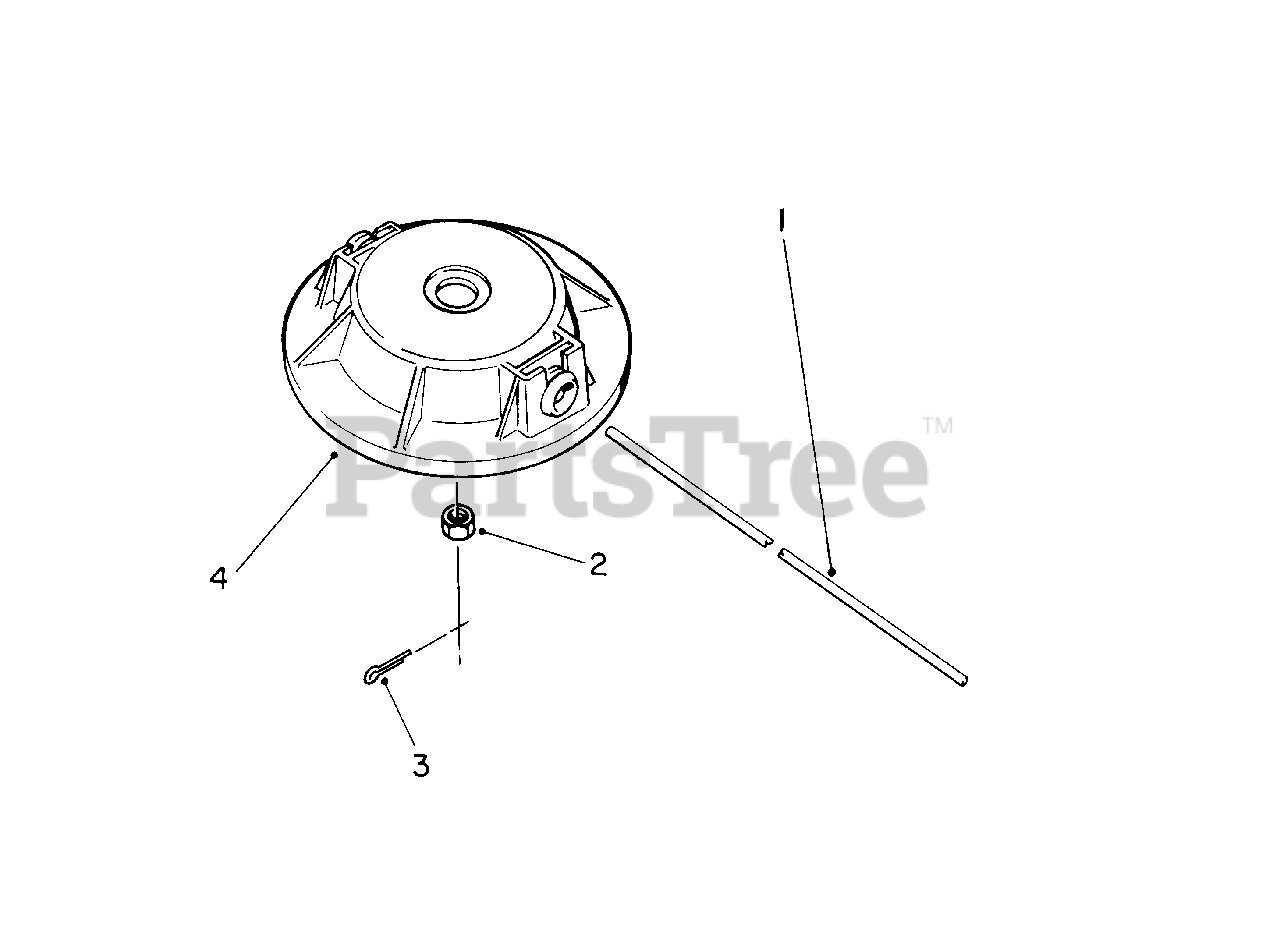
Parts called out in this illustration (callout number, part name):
1	Line-Cutting .105 Dia.
2	Nut Hex. L.H.
3	Pin-Cotter
4	Cutter Head Assembly
